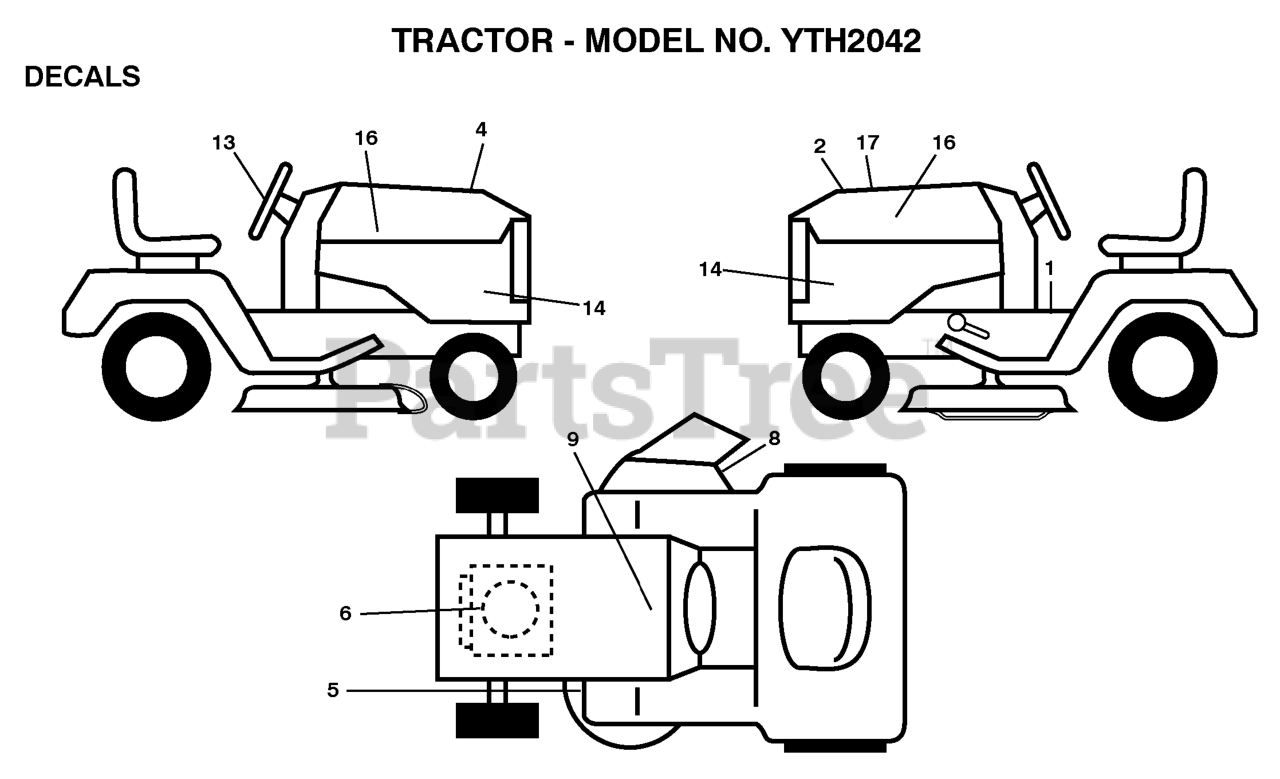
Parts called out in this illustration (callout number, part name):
1	DECAL.FENDER.OPER.TEX.
2	DECAL.HOOD.TOP.INSERT.
4	DECAL HOOD CUST. RESP.
5	DECAL V BELT SCHEMATIC
6	DECAL ENGINE HP
8	DECAL.WARN.KEEP.HAND.AWAY
9	DECAL BTRY SYMBOLS
13	DECAL.WHEEL.STRG.LGN.H
14	DECAL PANEL SIDE
16	DECAL.HOOD.NAMELOGO.HUSQ
17	DECAL, REPLACEMENT
